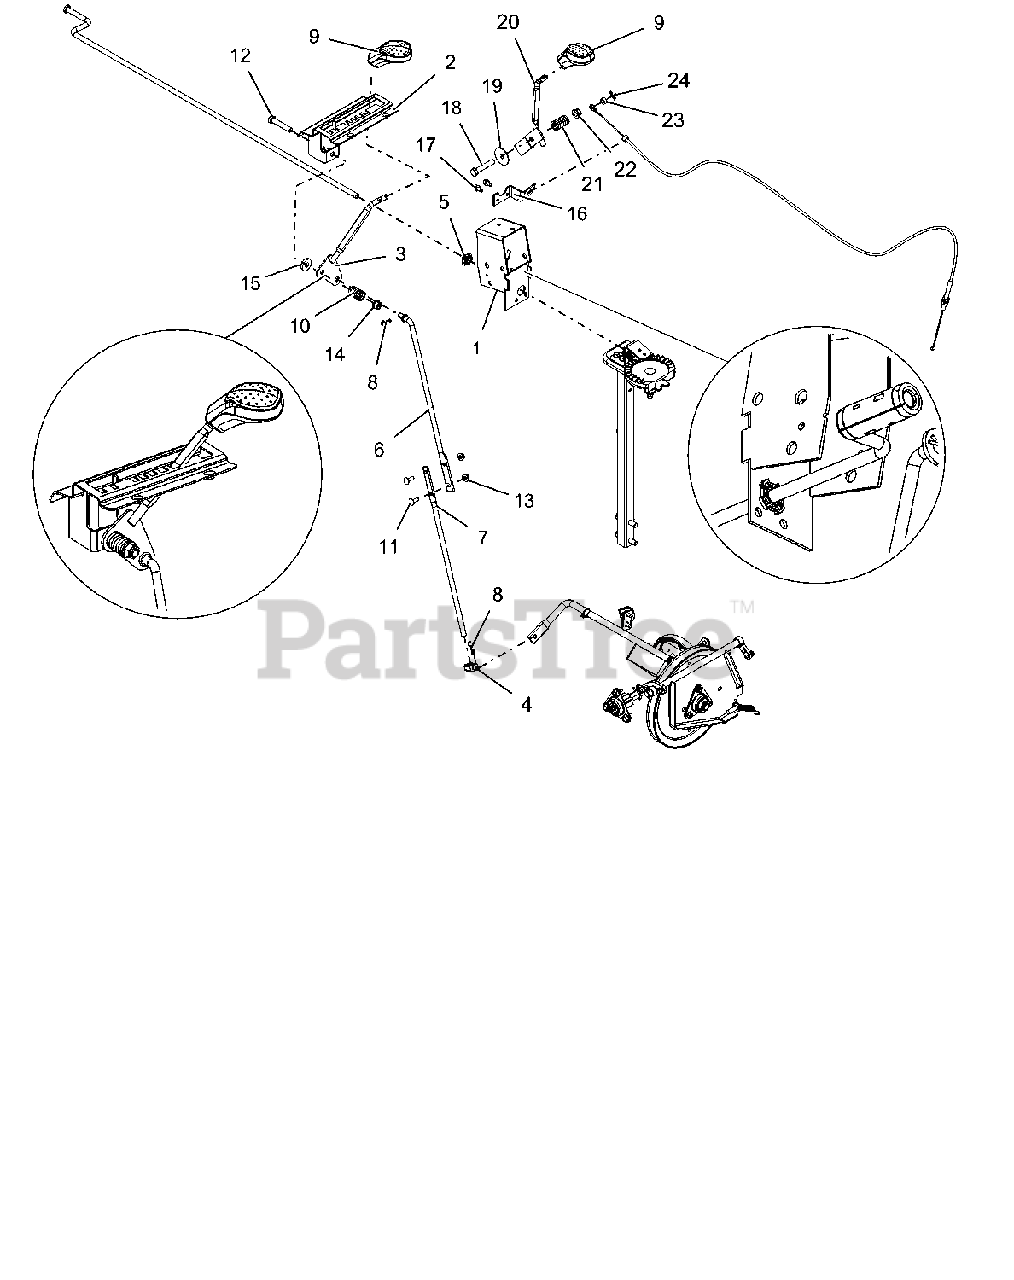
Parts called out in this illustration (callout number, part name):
1	WELDMENT, BRACKET INTERLOCK
2	WELDMENT, DETENT PLATE-COMPACT
3	LEVER, CONTROL-SHIFT(WELDMENT)
4	PIVOT,SHIFT ROD .375-16(TRUNN)
5	CRANK BUSHING, NYLON CHUTE BK
6	ROD, SHIFT - UPPER
7	ROD, SHIFT - LOWER
8	PIN-HAIR INT .08X.18X1.18 YWZC
9	KNOB, CONTROL, DASH
10	SG-COMP .125X.781X1.250
11	@BLT-RDHDSQNK .25-20X.75 G5YZ
12	@BLT-HEX .38-16X2.00 GR5 YWZC
13	@NUT-LK-CTR-FLG .25-20 YWZC
14	@NUT-LK-TOP-FLG .38-16 YWZC
15	WSHR-FL-STL .406X1.00X.188 YWZ
16	ANCHOR, DEFLECTOR CABLE
17	SCR-TAP .25-20X.50 HWH TR YWZ
18	@BLT-HEX .38-16X2.00 GR5 YWZC
19	WSHR-FL-STL .380X1.50X.062 YWZ
20	WELDMENT,SM DASH DEFL CONTROL
21	SG-COMP .125X.781X1.250
22	@NUT-LK-TOP-FLG .38-16 YWZC
23	BSHG-SLV .265X.500X.219
24	PIN-HAIR INT .06X.18X.77
